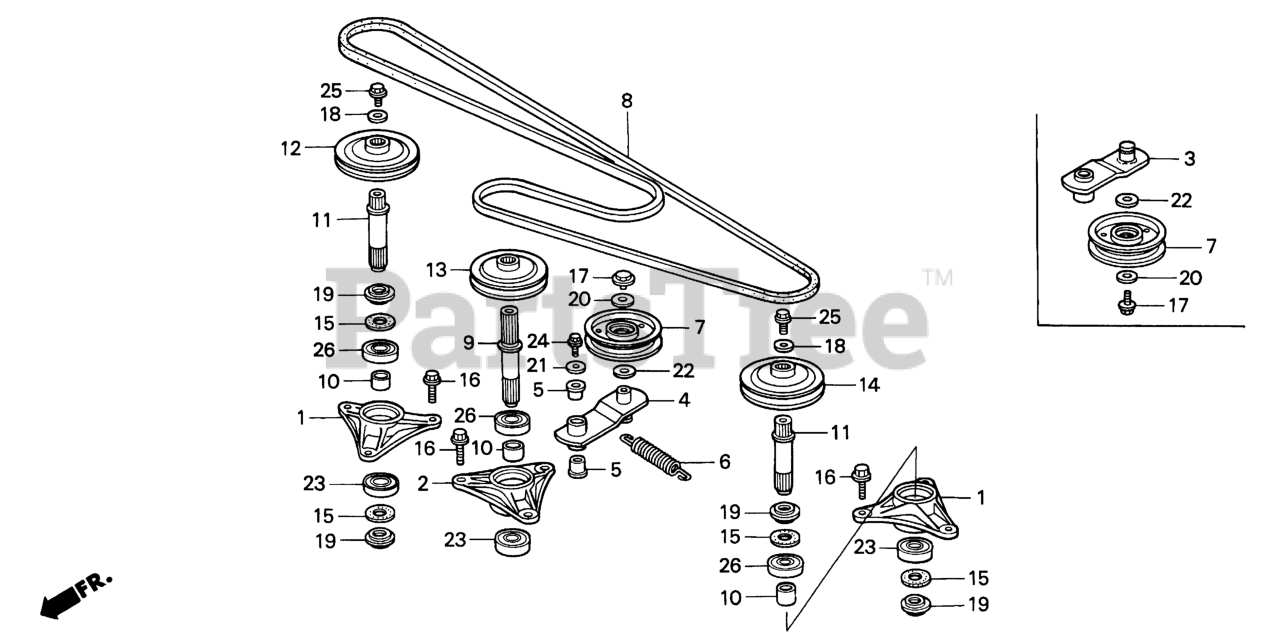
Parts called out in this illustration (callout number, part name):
1	HOUSING, BEARING
2	HOUSING, BEARING
3	ARM, TENSIONER (DECK)
5	BUSH, TENSIONER ARM (15X19X14)
6	SPRING, TENSIONER ARM
7	ROLLER, TENSIONER
8	V-BELT, BLADE (95)
9	SHAFT C, BLADE
10	COLLAR, BLADE SHAFT
11	SHAFT, BLADE
12	PULLEY, R. DECK
13	PULLEY, BLADE (120MM)
14	PULLEY, DECK
15	DUST SEAL, GAUGE ROLLER
16	BOLT, FLANGE (10X28)
17	BOLT, WHEEL
18	WASHER (10.5X27X4)
19	COLLAR, GAUGE ROLLER
20	WASHER (8MM)
21	WASHER (6MM)
22	WASHER, PLAIN (17.2MM)
23	BEARING, RADIAL BALL
24	BOLT, FLANGE (6X12) Use from Engine SN 2086984.
25	BOLT, FLANGE (10X16) (NA USE ALT:95700-10016-08)
26	BEARING, RADIAL BALL (6204UU)
